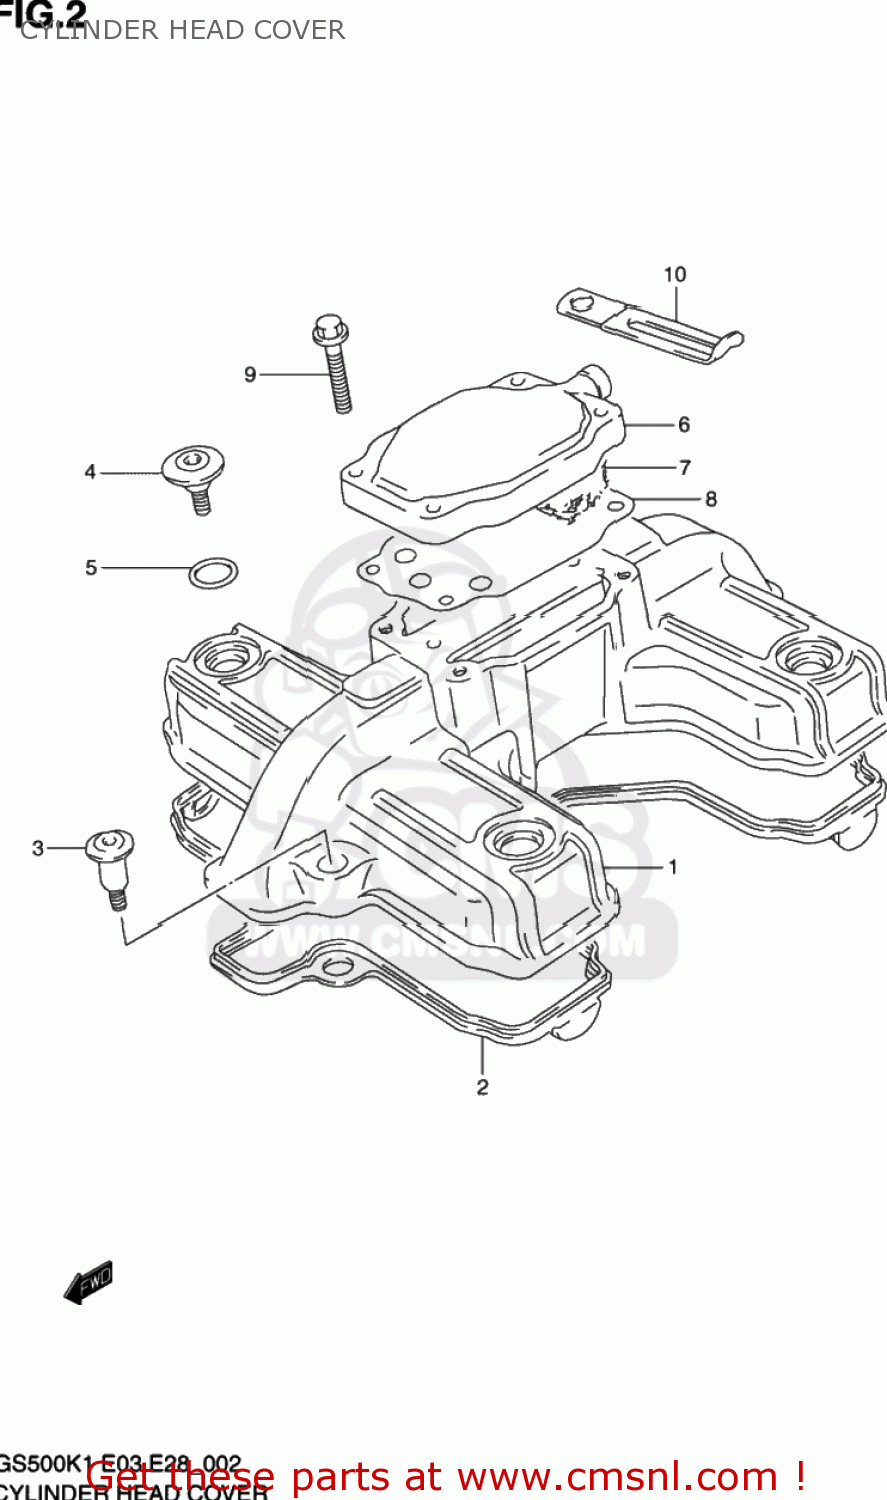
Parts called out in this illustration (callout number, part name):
1	COVER,CYLINDER HEAD
2	GASKET,CYLINDER HEAD COVER (NAS)
3	BOLT(7X31)
4	BOLT(7X17.5)
5	O RING(D:1.9,ID:14.5)
6	COVER,BREATHER
7	SEPARATOR,OIL BREATHER COVER
8	GASKET,BREATHER COVER (NAS)
9	BOLT
10	CLAMP(L:65)
